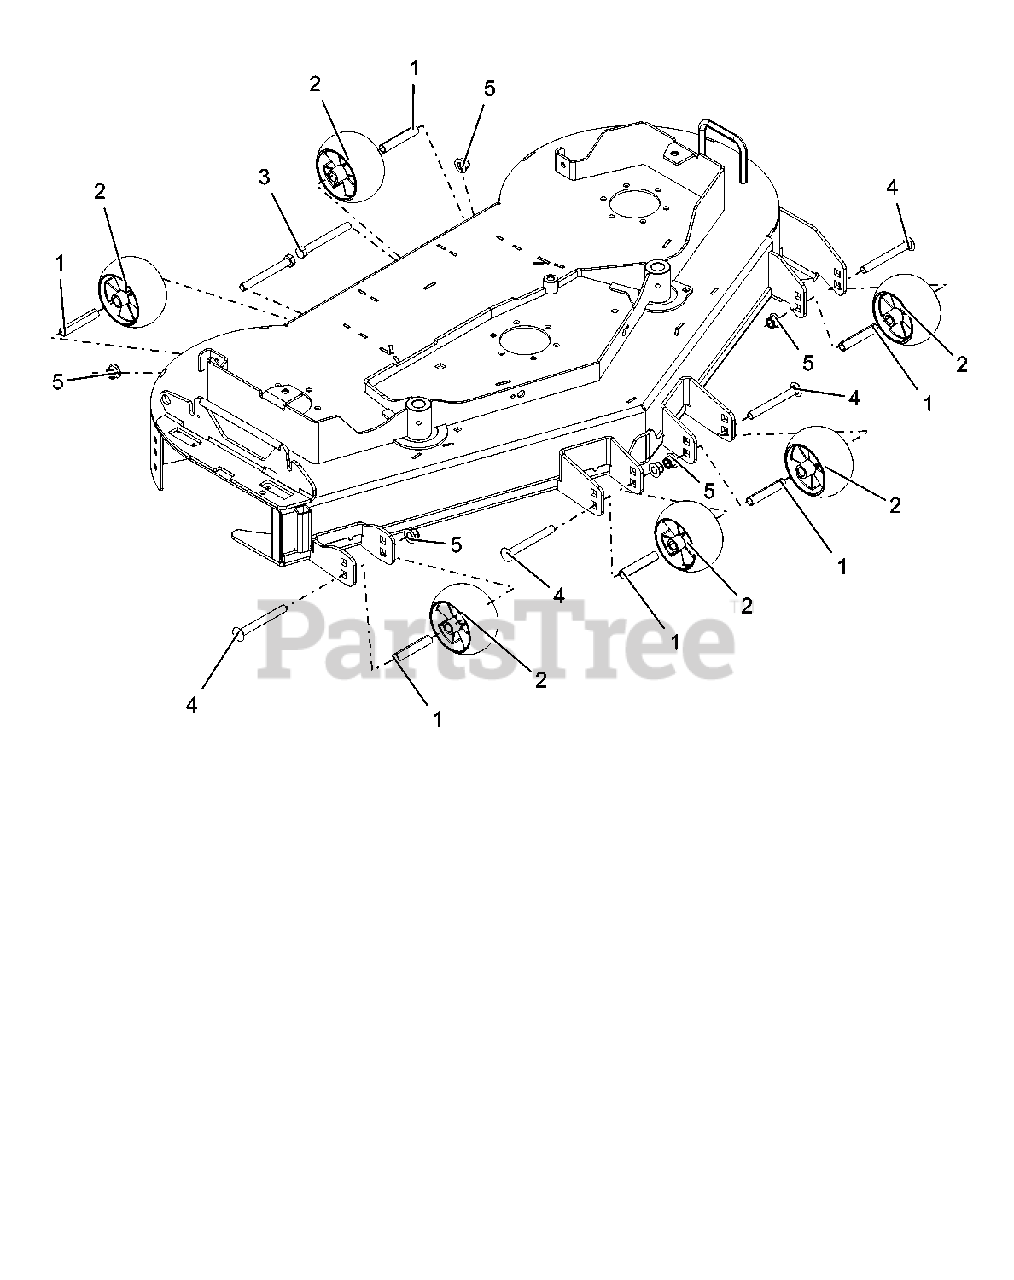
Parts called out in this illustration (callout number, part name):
1	SPACER, .510X.625X3.35
2	ANTI-SCALP WHEEL - 5X3 CTR
3	BLT-HEX .50-13X4.50 GR5 YWZC
4	BLT-RDHDSQNK .50-13X4.50 G5 YWZC
5	NUT-LK-NYL-FLG .50-13 YWZC
